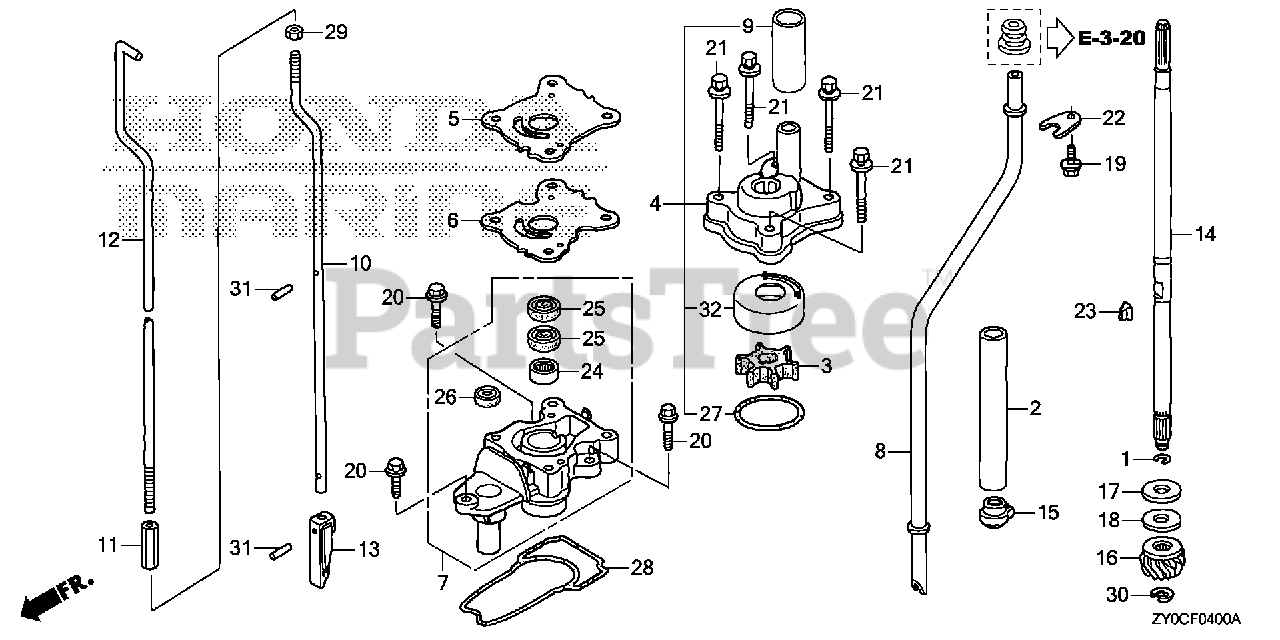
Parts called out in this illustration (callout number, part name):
1	CLIP, VALVE GUIDE
2	GUIDE, OIL (S,L)
3	IMPELLER, PUMP (UL)
4	HOUSING ASSY., IMPELLER
5	COVER, IMPELLER
6	GASKET, IMPELLER
7	HOUSING, WATER PUMP (S,L)
8	TUBE, WATER (L)
9	RING, WATER TUBE SEAL
10	ROD B, SHIFT (L)
11	JOINT, SHIFT ROD
12	ROD A, SHIFT (L)
13	ROD, PUSH
14	SHAFT, VERTICAL (L)
15	SLINGER, OIL (UL)
16	GEAR, PINION
17	WASHER A, THRUST BEARING
18	WASHER B, THRUST BEARING
18	WASHER C, THRUST BEARING
19	BOLT, FLANGE (6X12) Use from Frame SN 1005249.
20	BOLT, FLANGE (6X20) (ENGINE NO.)
21	BOLT-WASHER (6X50)
22	PLATE, WATER TUBE SETTING
23	KEY, WOODRUFF
24	BEARING, NEEDLE (15X21X12)
25	SEAL, WATER (15X24X5)
26	SEAL, WATER (6MM)
27	O-RING (42.2X2.4)
28	O-RING, WATER PUMP HOUSING
29	NUT, HEX. (6MM)
30	E-RING (8MM)
31	ROLLER (2.5X11.8)
32	LINER, PUMP
